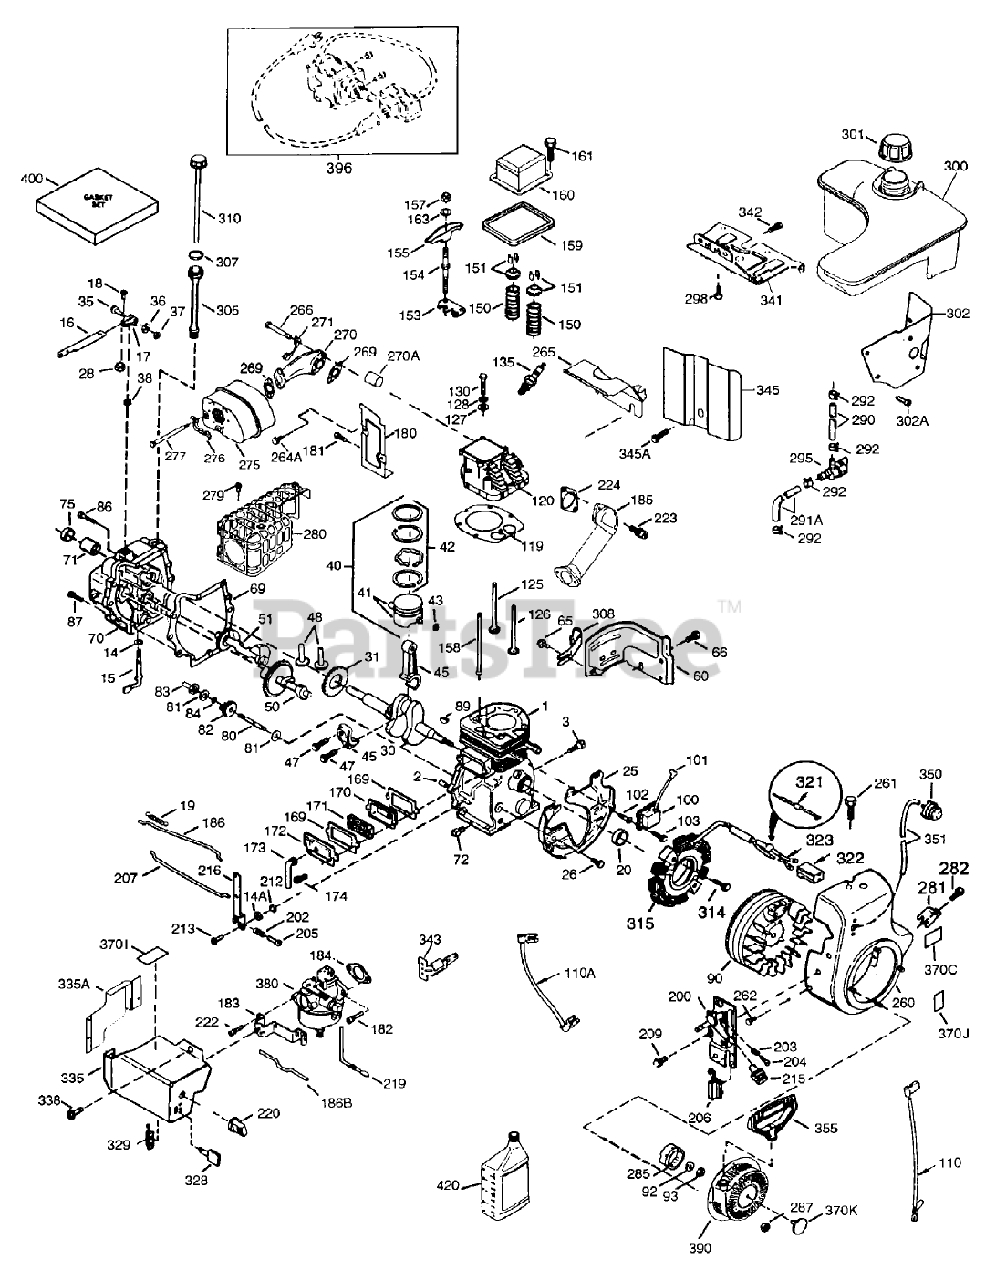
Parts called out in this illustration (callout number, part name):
1	Cylinder (Incl. 2, 20, 72 80)
2	Pin-Dowel
3	Screw (1/4-20x1/2)
14	Washer-Flat
14A	Washer
15	Governor Rod (Incl. Ref.#14 38)
16	Governor Lever
17	Clamp-Lever, Governor
18	Screw (T-15, 8-32x7/16)
19	Throttle Spring
20	Seal-Oil
25	Baffle-Housing, Blower
26	Screw (1/4-20x19/32)
28	Nut-Lock
30	Crankshaft
31	Counterbalance Gear
35	Screw
36	Washer-Lock
37	Nut-Lock
38	Ring-Retaining
40	Piston Pin and Ring ASM (STD)
40	Piston Pin and Ring ASM (.010)
40	Piston Pin and Ring ASM (.020)
41	Piston Pin Ass-y(Std.)(Incl. 43)
41	Piston Pin Ass-y (.010" OS)(Incl. 43)
41	Piston Pin Ass-y.(.020" OS)(Incl. 43)
42	Ring Set (STD)
42	Ring Set (.010)
42	Ring Set (.020)
43	Retaining Ring-Piston Pin
45	Connecting Rod ASM (Incl. Ref. #47)
47	Bolt-Rod, Connecting
48	Lifter-Valve
50	Camshaft
51	Counterbalance Weight
60	Extension-Housing, Blower
65	Screw (10-24 x 9/16)
66	Screw
69	55072/75/86/89 TWO
70	Cylinder Cover (Incl. Ref. #14, 15, 38, 71, 75)
71	2025A77 WIZARD ROTA
72	Plug-Drain, Oil (SQH 1/4-18)
75	Seal-Oil
80	Governor Shaft
81	Washer
82	Gear-Asm Governor
83	Governor Spool
84	Ring-Retaining
86	Screw (1/4-20x1-3/16)
87	Screw (1/4-20x1-11/16)
89	Key-Flywheel
90	Flywheel (W/Ring Gear)
92	Washer-Belleville
93	Nut-Flywheel
100	Solid State ASM
101	Cover-Spark Plug
102	Stud-Mounting, Solid State
103	Screw (T-15, 10-24 x 15/16)
110	Wire-Ground
110A	Wire-Ground
119	Cylinder Head Gasket
120	Cylinder Head
125	Valve-Exhaust (STD)
125	Valve-Exhaust (1/32)
126	Valve-Intake (STD)
126	Intake Valve (1/32)
127	Washer-Flat
128	Washer-Belleville
130	Screw (5/16-18 X 2-1/2)
135	Spark Plug-Resistor (R N 4C)
150	Spring-Valve
151	Keeper-Spring, Valve
153	Guide-Rod, Push
154	Stud-Arm, Rocker
155	Arm-Rocker
157	Nut-Jam
158	Rod-Push
159	Gasket-Cover, Rocker Arm
160	Cover-Arm, Rocker
161	Screw
163	Washer
169	Gasket-Cover, Valve
170	Body-Breather
171	Element-Breather
172	Cover-Valve
173	Tube-Breather
174	Screw
180	Extension-Housing, Blower
181	Screw (10-24 x 9/16)
182	Screw (T-30, 1/4-20 X 27-32)
183	Bracket-Choke
184	Gasket-Carburetor To Intake Pipe
185	Pipe-Intake
186	Governor Link
186B	Spring-Choke
200	Bracket-Control (Incl. Ref. #203, 204 and 206)
202	Compression Spring
203	Spring-Compression
204	Screw (T-10, 5-40x7/16)
205	Screw
206	Terminal
207	Choke Link
209	Screw (10-32 x 1/2)
212	Bushing
213	Screw
215	Knob-Control
216	Lever-Adjusting
219	Rod-Choke
220	Knob-Control
222	Screw (10-32 x 1/2)
223	Screw (T-30, 5/16-18 X 7/8)
224	Gasket-Pipe
260	Blower Housing
261	Screw (1/4-20 X 5/8)
262	Screw
264A	Screw
265	Cover-Head, Cylinder
266	Screw (5/16-18 X 1-9/32)
269	Gasket-Manifold, Exhaust
270	55107 SNWTHWR ATTCH
270A	Liner-Port, Exhaust
271	Plate-Locking
275	Muffler
276	Locking Plate
277	Screw (5/16-18 X 4-1/2)
279	Screw
280	Cylinder (Incl. 2, 20 150)
281	Screw
282	Screw (8-32 x 3/8)
285	Cup-Starter
287	Nut and Lock Washer (1/4-28)
290	Line-Fuel
291A	Line-Fuel (8.62)
292	Clamp-Line, Fuel
295	Valve-Shut Off, Fuel
298	Screw (1/4-15x7/8)
300	Fuel Tank (Incl. 292 and 301)
301	Cap-Fuel
302	Extension-Tank, Fuel
302A	Screw (10-32 x 1/2)
305	Tube-Fill, Oil
307	O-Ring
308	Clip-Tube, Fill
310	Dipstick
314	Screw (1/4-20 x 3/4)
315	Alternator Coil (3/5)(Incl. 321-323)
321	Diode
322	Body-Connector
323	Terminal
328	Key-Ignition
329	Terminal
335	Spring
335A	Cover-Carburetor
338	Screw (10-32 x 1/2)
341	Bracket-Tank, Fuel
342	Screw (5/16-18 X 7/8)
343	Bracket-Switch, Key
345	Baffle-Heat
345A	Screw (10-32 x 1/2)
350	Primer ASM
351	Line-Primer
355	Handle-Starter, Mitten Grip
370C	Decal-Primer, International Symbol
370I	Decal-Warning (Bilingual)
370J	Decal-Choke
370K	Decal-Tecumseh Logo for Top of Recoil Starter
380	Carburetor (Incl. Ref.# 184)
390	Starter-Rewind
396	Starter-Electric (110 Volt)
400	Gasket Set (Incl. Items Marked PK in Notes) Incl. part #-s 27272A (1), 27 896A (2), 33263 (1), 33515A (1), 34265 (1), 35317 (1), 35683 (1), 35762 (2), 35952 (1), 36333 (1), 36352 (1), 36358 (1), 36930 (1), 36932 (1), 36942 (1)
420	Oil-Engine, S A E 5W30
